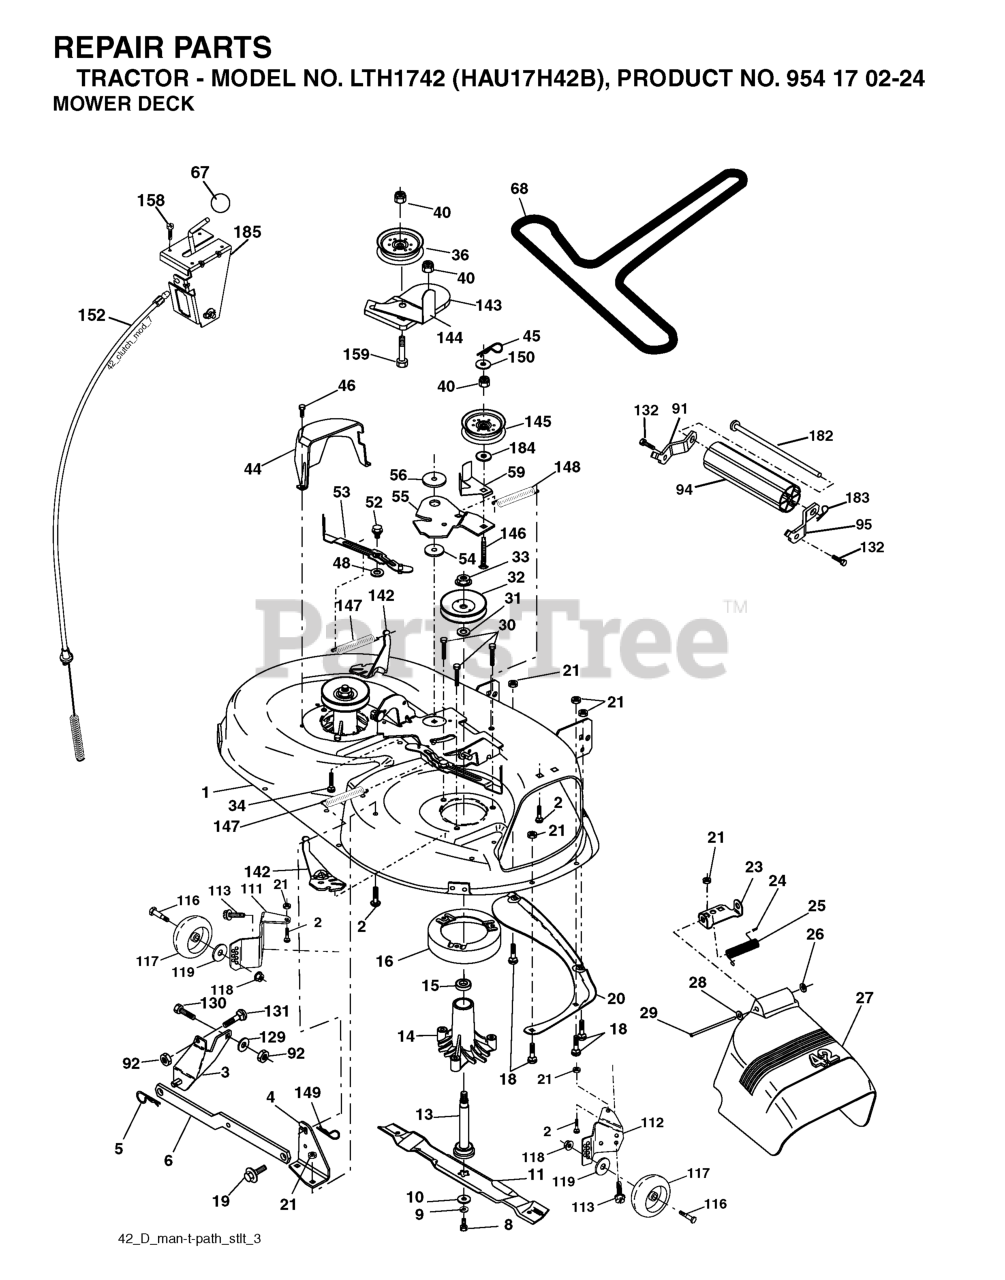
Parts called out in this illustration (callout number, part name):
1	42" DECK KIT
2	RP BOLT 5/16-18 X3/4 ZN/YEL GR
3	BRKT ASM SWAY BAR
4	BRACKET SWAY BAR 42" DECK
5	RETAINER-SPRNG RB
6	BAR SWAY DECK
8	BLADE BOLT
9	LOCKWASHER
10	WASHER.BLADE
11	42" HI-LIFT BLADE
13	SHAFT ASM VENT
14	HOUSING.MANDREL.VENTED (MACHD)
16	STRIPPER.MANDREL.ROUND.BLACK
18	BOLT
19	BOLT SHD 5/16-18
20	BAFFLE.VORTEX
21	LOCKNUT
23	BRKT, DEFL. MOWER
24	CAP-SLEEVE LT
25	SPRING TORSION
26	NUT PUSH M
27	SHIELD DEFLECTOR
28	Washer 11/32 x 5/8 x 16 Ga SD
29	ROD.HINGE
30	SCREW, WASHER HEAD
31	WASHER.SPACER.MANDREL
32	PULLEY/MANDREL
33	NUT, FLG TOPLOCK 9/16"
34	BOLT.3/8-16X1.50
36	FLAT IDLER PULLEY
40	NUT LOCK FLG 3/8-16 UNC
44	GUARD MANDREL LH BLACK
45	RETAINER M
46	SCREW.1/4-20X5/8
52	BOLT.SHOULDER.5/16-18
53	ARM BRAKE ASSY
55	ARM IDLER 42" MOWER LT/YT
56	SPACER.RETAINER.MOWER
59	GUARD, BELT
67	KNOB T (3/8 HOLE)
68	BELT V SECONDARY
91	BRACKET ASM NOSEROLLER LH
92	NUT
94	NOSE ROLLER
95	BRACKET ASM NOSEROLLER RH
111	BRACKET, WHEEL
112	BRACKET, WHEEL
113	BOLT.5/16HEX.WHS.HD
116	BOLT M
117	WHEEL.GAUGE.STANDARD
118	LOCKNUT
119	WASHER.5/16.FLAT.STE.STD.
129	WASHER
131	BOLT D
132	SCREW, 3/8-16X3/4
142	ARM SPRING BRAKE MOWER
143	BRACKET, ARM IDLER
144	DNO KEEPER.BELT.42".CLUTCH.CBL
145	PULLEY
146	BOLT, CARRIAGE IDLER BLACK
147	SPRING EXTENSION
148	IDLER RETURN SPRING
149	SPRING.RETAINER.YELLOW.ZINC
152	CLUTCH CABLE 42"
158	SCREW
182	ROD ROLLER NOSE STANDARD
183	SPRING RETAINER
184	WASHER
185	HEAD ASM. CABLE CLUTCH
